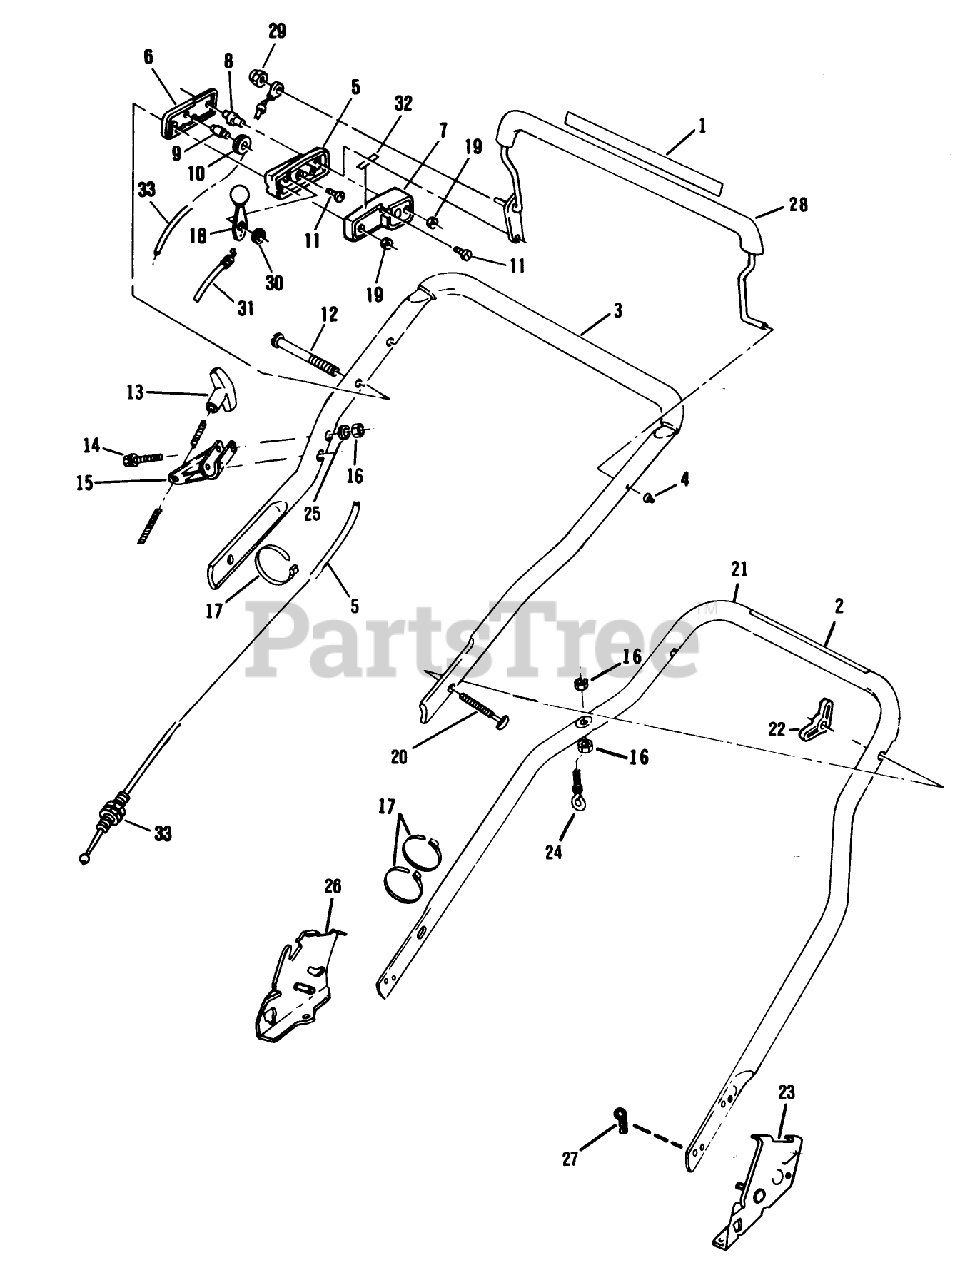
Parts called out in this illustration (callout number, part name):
2	Decal-Starting Inst.
3	HANDLE-TOP *G
8	COLUMN
9	PIN SKF
10	PULLEY PL
11	SCREW
12	SCREW
13	HANDLE START UM&D
16	LOCKNUT E
18	LEVER&KNOB AY WES
19	NUT C/LOCK E
20	BOLT QUALITY
22	NUT-WING
24	EYE BOLT WAS MFG
25	WASHER
27	HAIR PIN
29	NUT ACORN
30	WASHER-SPRING
31	CABLE THROT WES
33	CONTROL CABLE WES
